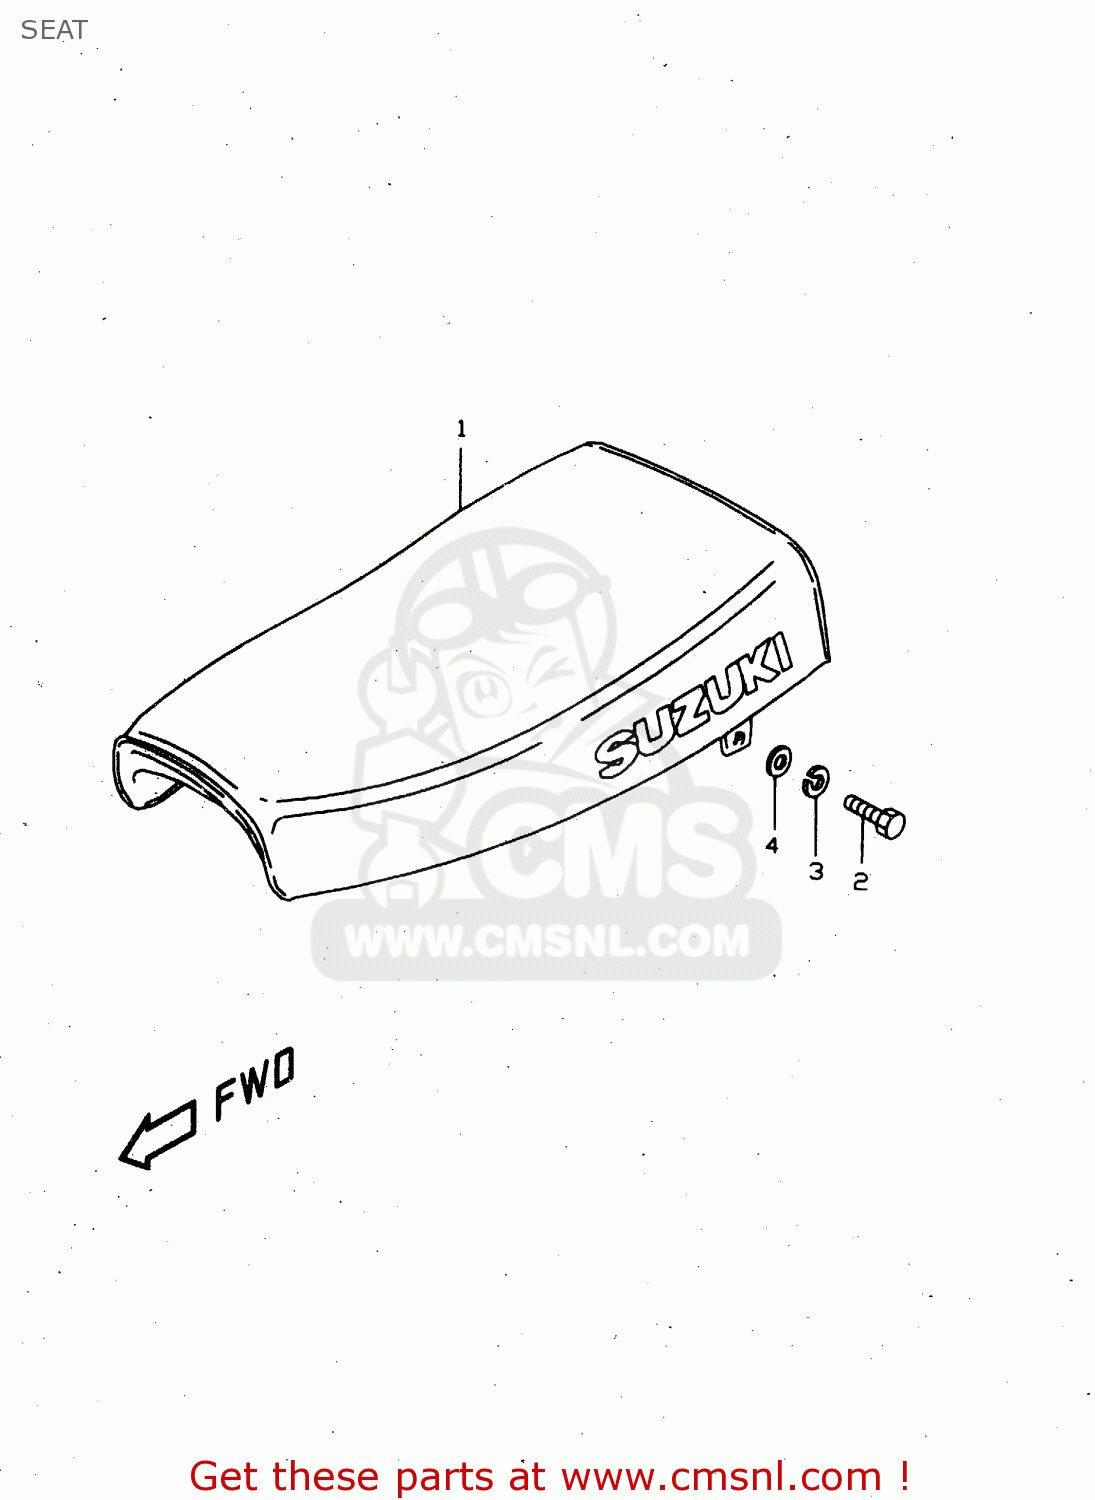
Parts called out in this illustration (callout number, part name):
1	SEAT SET
2	BOLT
3	LOCK WASHER
4	WASHER
